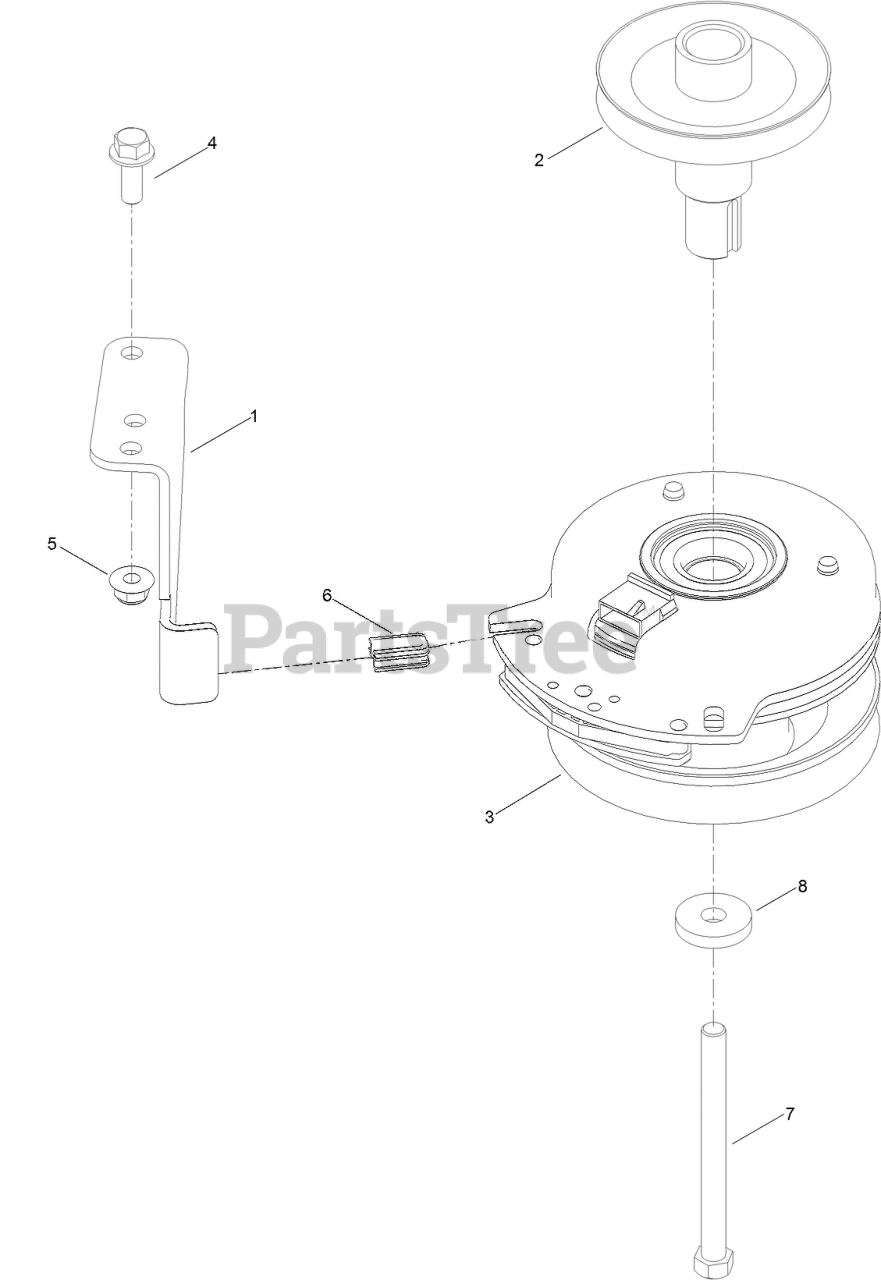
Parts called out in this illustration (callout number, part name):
1	STOP-CLUTCH (WIDE)
2	PULLEY-ENGINE
3	CLUTCH-PTO
4	SCREW-HHF
5	NUT-HF, NI
6	ISOLATOR-CLUTCH
7	SCREW-HH
8	WASHER
